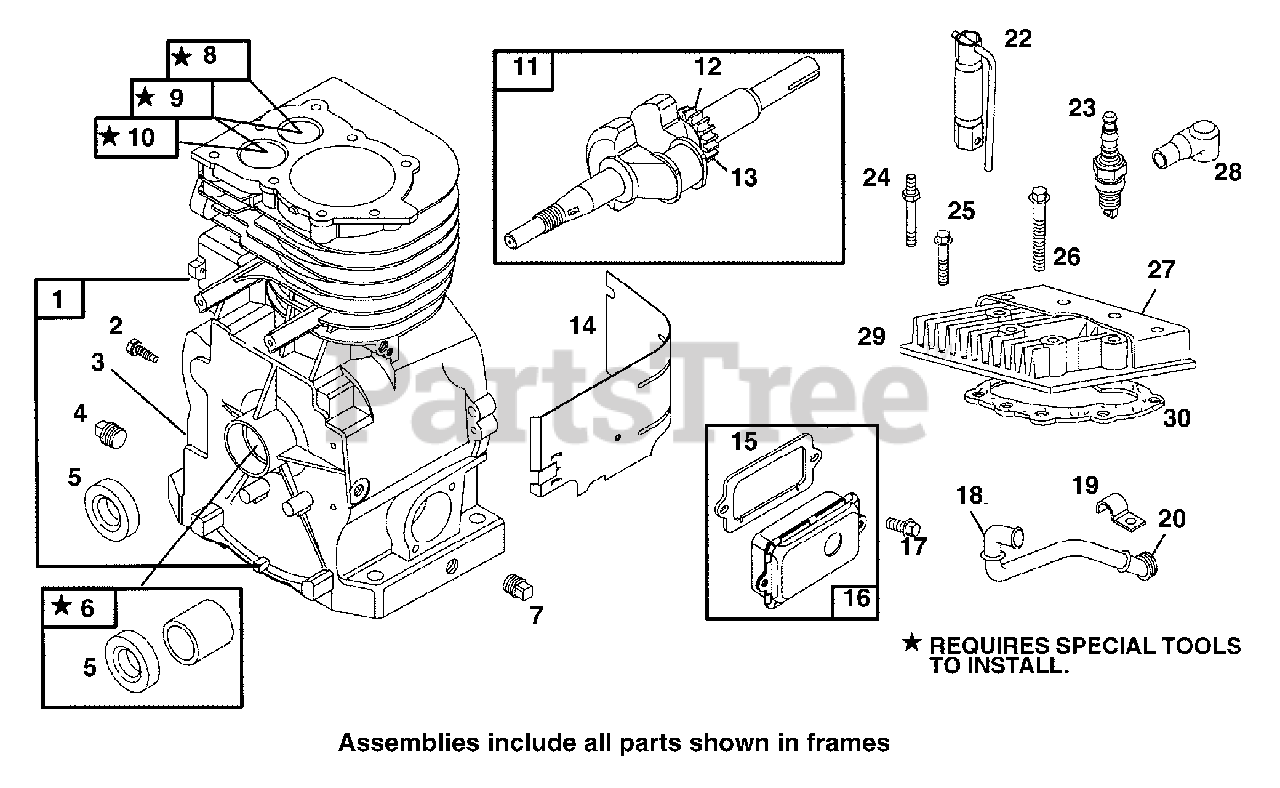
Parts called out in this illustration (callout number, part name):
1	Cylinder Assembly
2	Hex Screw
3	Gov. Crank Bushing
4	Oil Drain Plug
5	Oil Seal
6	Bushing/Seal Kit
7	Oil Drain Plug
8	Valve Seat (Exhaust)
9	Guide Bushing (Exhaust Valve)
10	Valve Seat (Intake)
11	Crankshaft
12	Timing Key
13	Timing Gear
14	Cylinder Shield
15	Breather Gasket
16	Breather Assembly
17	Hex Screw
18	Grommet
19	Breath Tube Support
20	Grommet
22	Spark Plug Wrench
23	Spark Plug
24	Hex Drive Stud
25	Hex Screw (2-1/16")
26	Hex Screw (2-7/8")
27	Cylinder Cover
28	Spark Plug Boot
29	Cylinder Head
30	Cylinder Head Gasket
